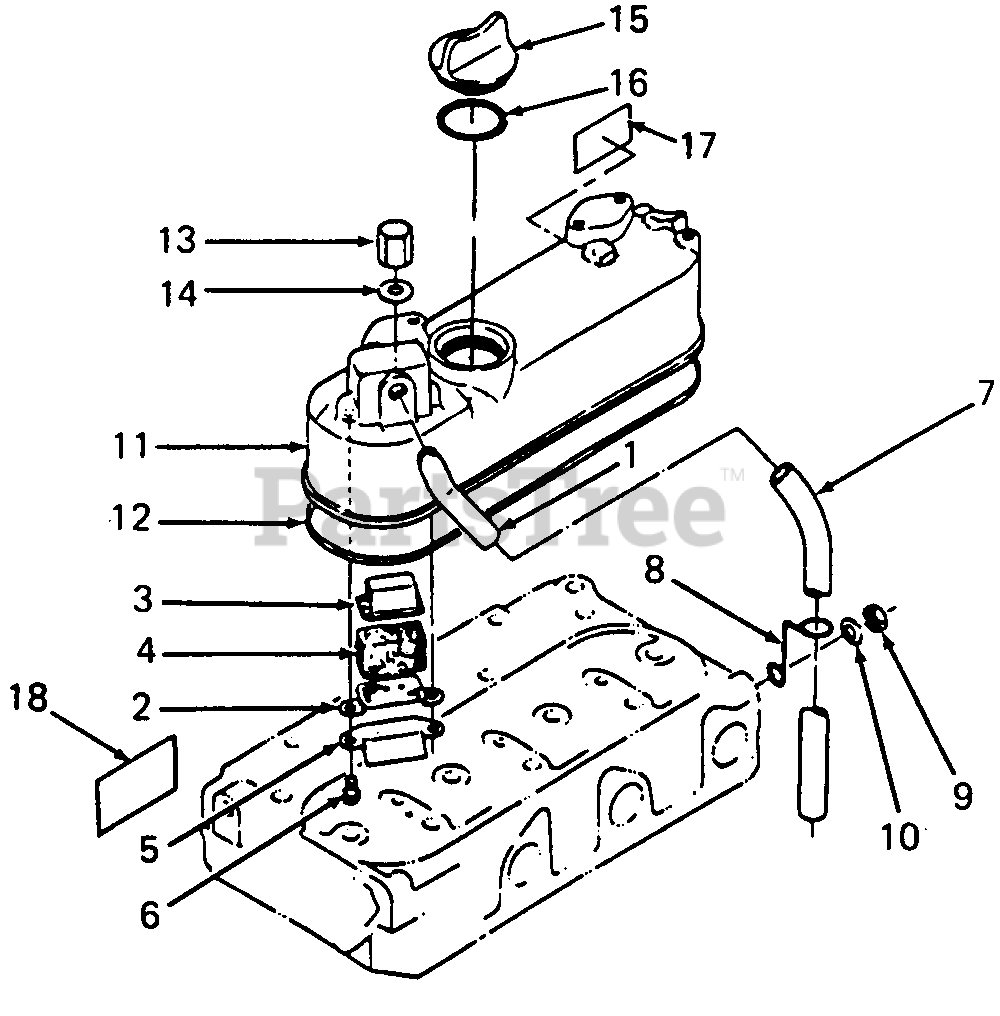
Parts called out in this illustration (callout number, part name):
1	Joint, Breather Pipe
2	Plate, Breather Element - 1
3	Plate, Breather Element - 2
4	Element, Breather
5	Shield, Breather Oil
6	Screw, Hex Cap w/Washer
7	Tube, Breather, 15.75 Lg
12	Gasket, Head Cover
15	Plug, Filler
15	PLug, Filler
16	O-Ring, 1-3/16 X 1-7/16
